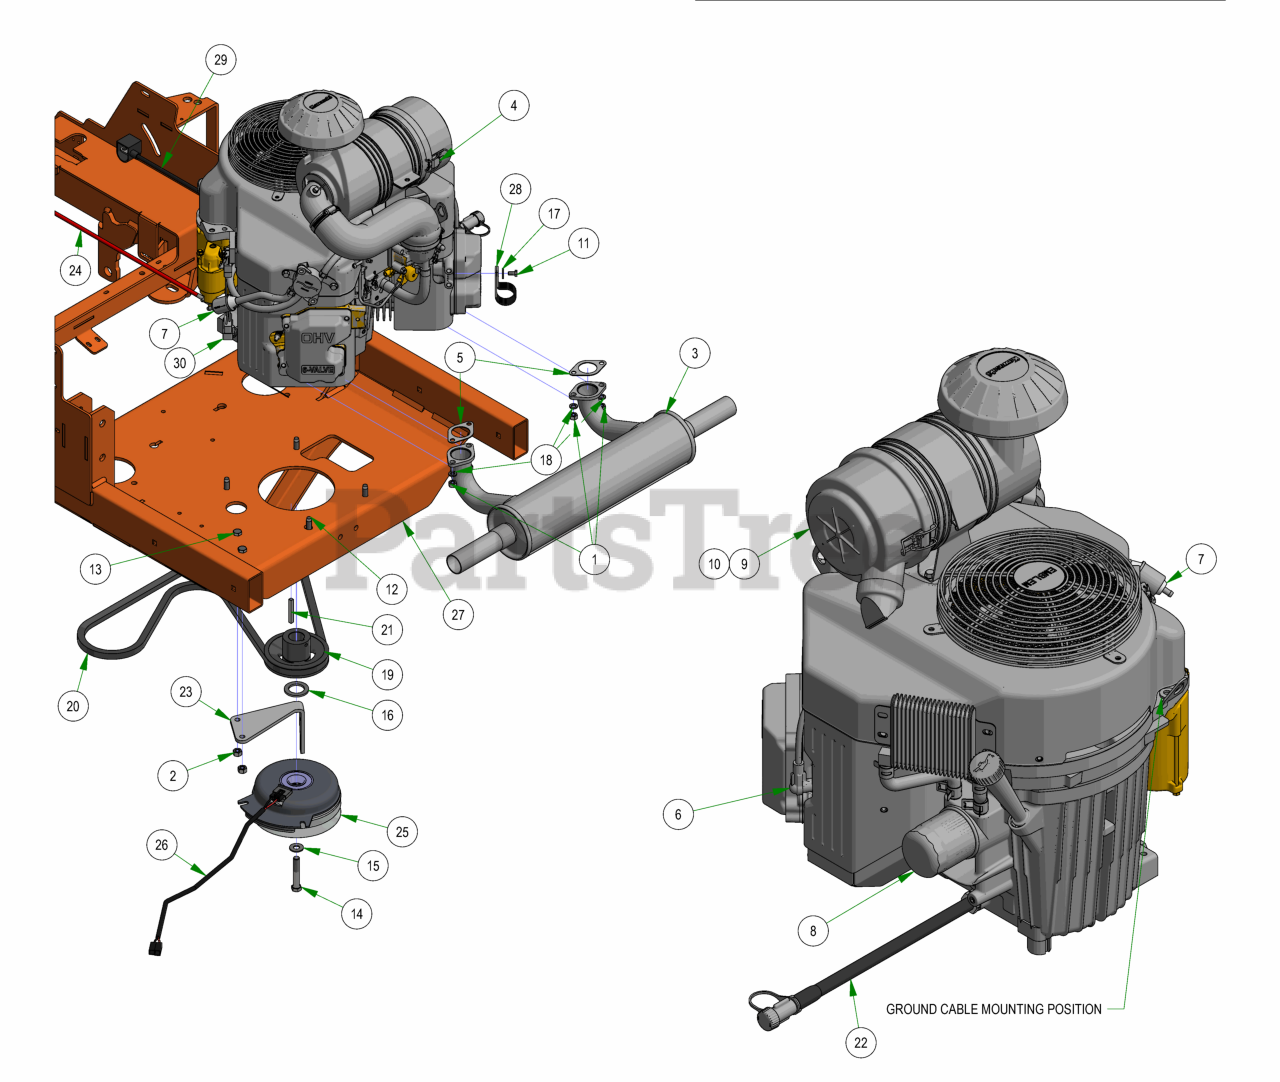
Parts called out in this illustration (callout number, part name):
1	M8-1.25 DIN 934 HEX NUT (CL.8) ZINC
2	3/8-16 HEX NUT ZINC
3	2019 Rebel/Rogue Kawasaki 1000 Muffler
4	Kawasaki FX1000 Engine
5	Exhaust Gasket
6	Spark Plug - Kawasaki
7	Universal Inline Fuel Filter
8	Oil Filter
9	Canister Air Filter- Outer
10	Canister Air Filter- Inner
11	M6-1.0 X 12MM DIN 933 HEX TAP BOLT (CL 8.8) ZINC
12	3/8-16 X 1-1/8HEX WASHER UNSLOT SERRATED (TRI-LOB) TRS
13	3/8-16 X 1-1/4 HEX CAP SCREW (GR.5) ZINC
14	7/16-20 X 2-1/2 HEX Bolt GR 8 W/ Patch
15	3/8 FLAT WASHER USS (1" OD) ZINC
16	1.140 ID X 1.750 OD X .132 THICK FLAT WASHER PLAIN
17	1/4 USS FLAT WASHER (3/4 OD) ZINC
18	5/16 SPLIT LOCKWASHER ZINC
19	4 3/4 Motor Pulley
20	2019 Rogue Pump Belt 68"
21	1/4 X 2 SQ MACHINERY KEY 1018 STL PLAIN
22	Kawasaki Oil Drain
23	PTO Engager Holder
24	24" Red Battery Cable
25	Clutch Assembly
26	Clutch Pigtail
27	2023 Rogue Frame - Painted
28	Diesel Hydraulic Hose Clamp
29	Starter Cable
30	2019 Harness Adaptor-Gen2 FX-ALL
